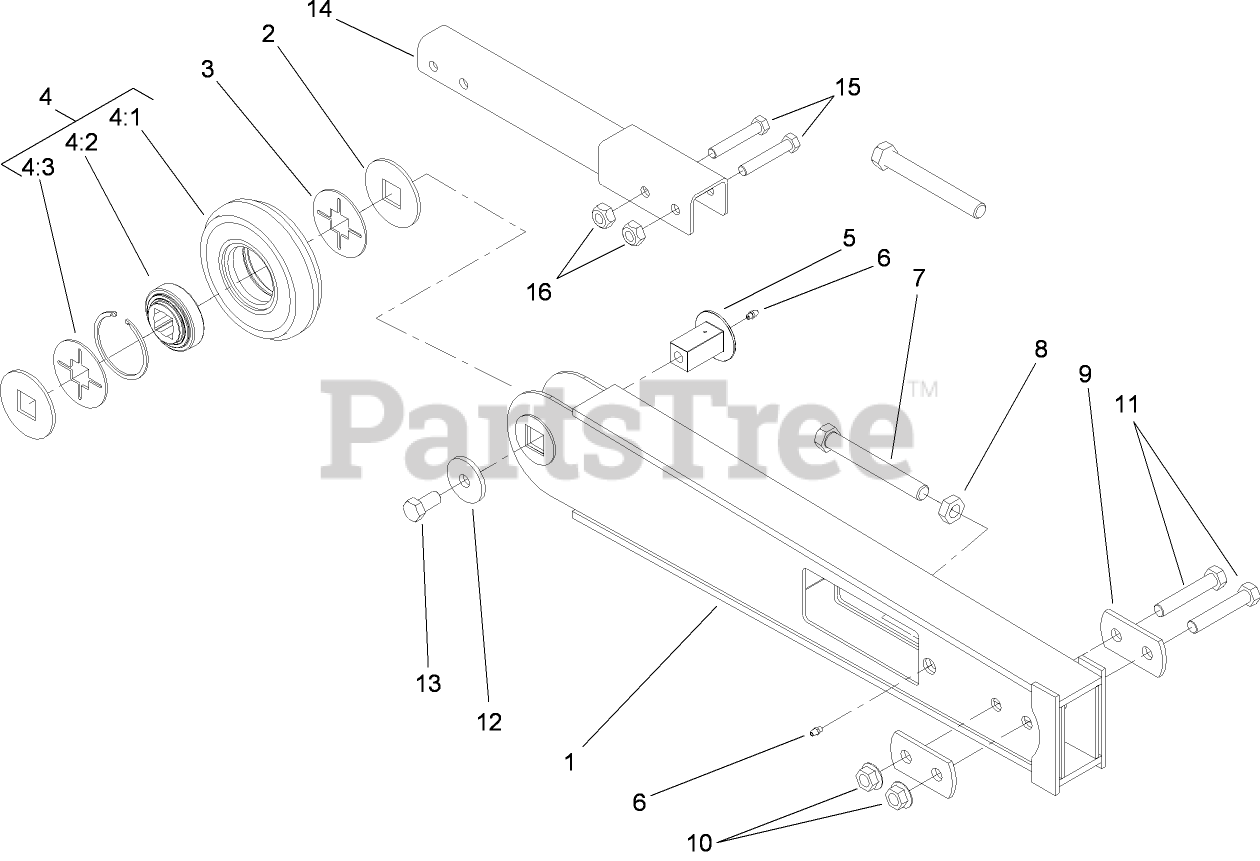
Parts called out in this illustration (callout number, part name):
1	BOOM ASM
2	CAP-ROLLER
3	SPACER-ROLLER
4	TRENCHER ROLLER ASM
4:1	ROLLER-NOSE
4:2	BEARING
4:3	RING-RETAINING
5	AXLE-ROLLER
6	FITTING-GREASE
7	BOLT-ADJUSTMENT
8	NUT-JAM
9	PLATE-SUPPORT
10	NUT-FLANGE
11	SCREW-HH
12	WASHER
13	SCREW-HH
14	SAFETY BAR EXTENSION ASM
15	SCREW-HH
16	NUT-HEX
